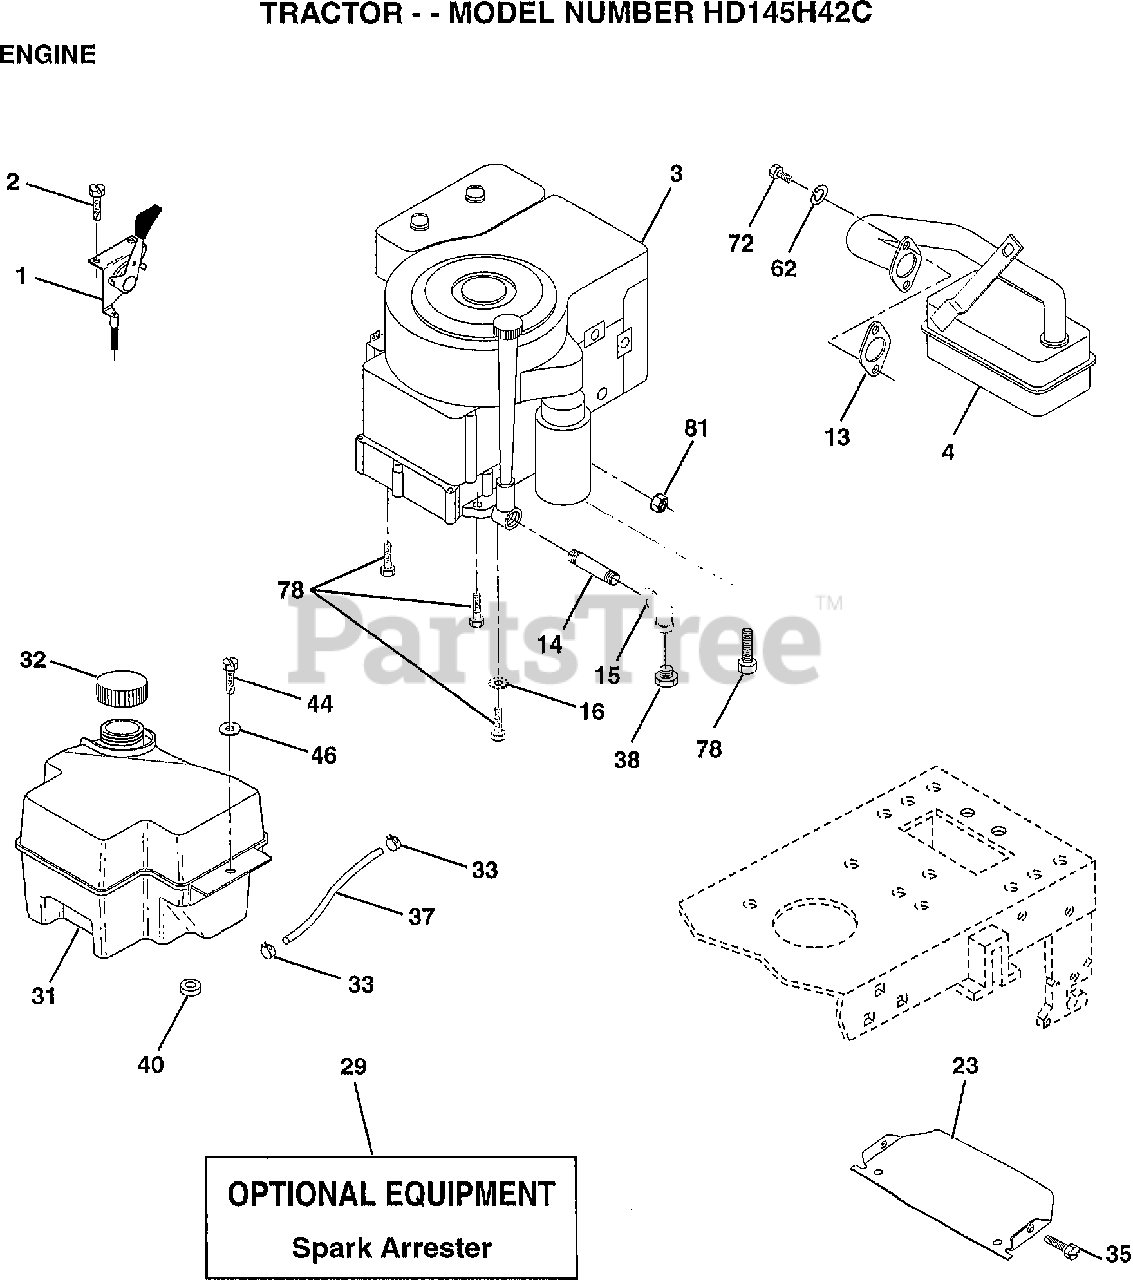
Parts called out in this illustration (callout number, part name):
1	CONTROL THROTTLE
2	SCREW LT
4	MUFFLER
13	GASKET ENG 1 313 LD TIN PLATED
14	PIPE NIPPLE
15	ELBOW
16	LOCKWASHER
23	SHIELD-HEAT
32	CAP ASM FUEL
33	HOSE CLAMP
35	SCREW
37	LINE FUEL
44	SCREW HEX CRT
46	WASHER
62	LOCKWASHER
72	SCREW
78	SCREW
81	NUT
